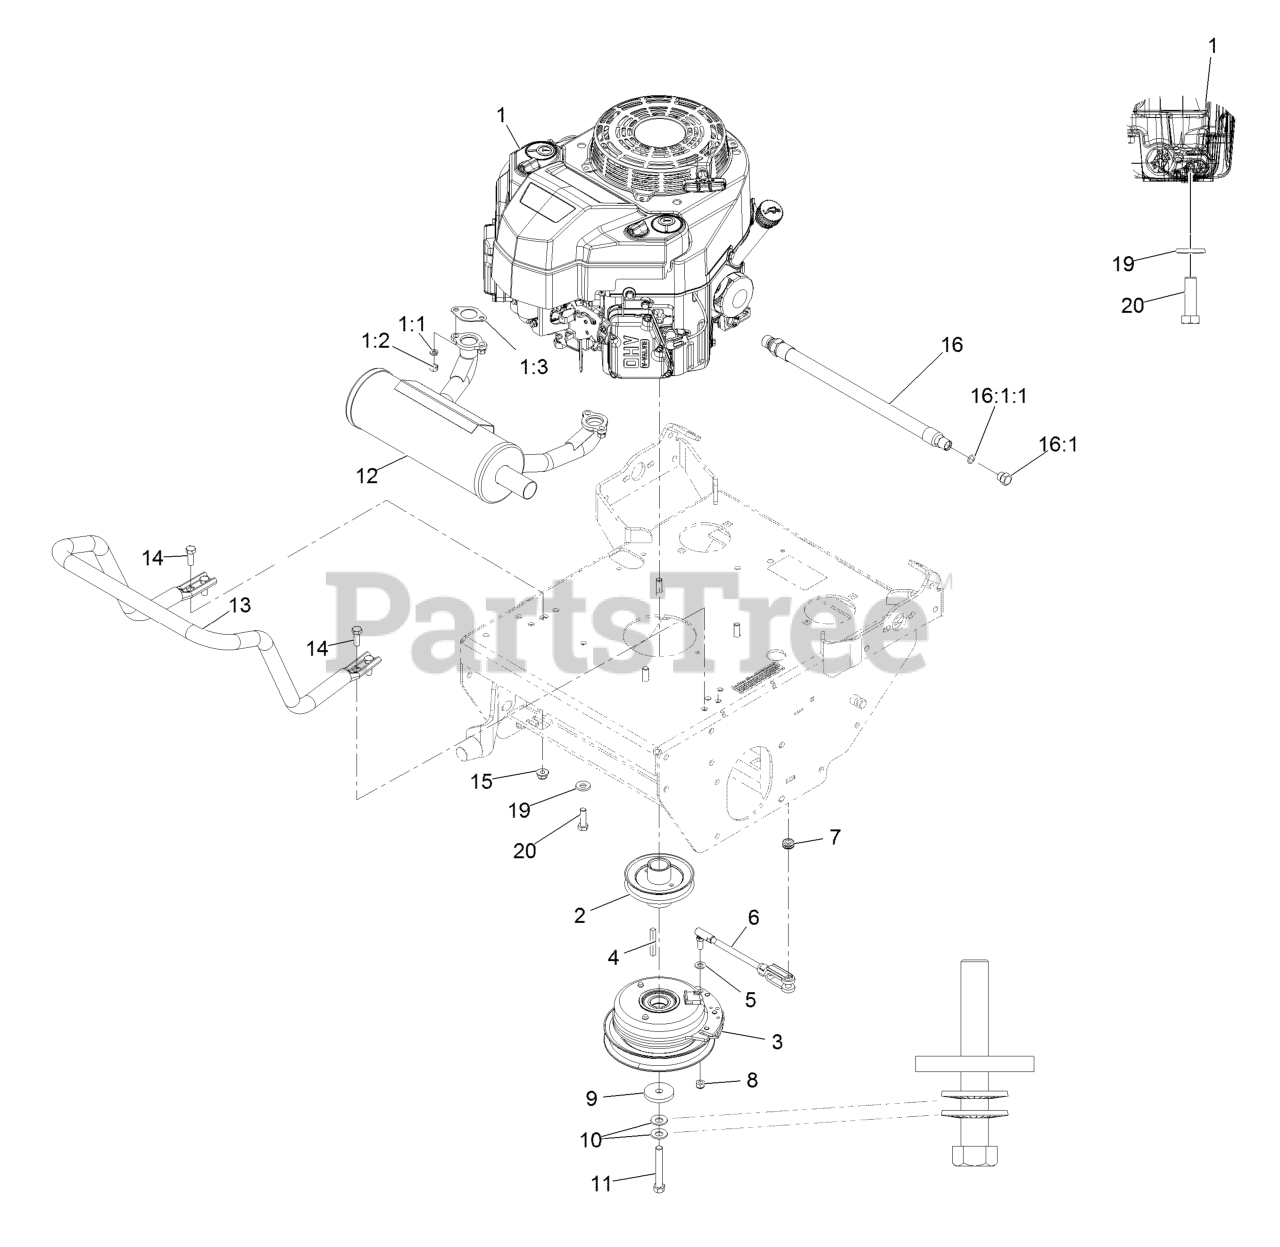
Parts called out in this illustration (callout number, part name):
1:1	Washer-Spring Lock M8
1:3	Gasket-Exhaust
2	Sheave, W/ Hub
3	Clutch, 105 Ft/Lbs, 1.13
4	Key-Machine 1/4 X 1/4 X 2
5	Washer-5/16 SAE
6	ASM, Clutch Anchor
7	Grommet
8	Nut-Lock 5/16-24
9	Washer-Clutch
10	Washer-Spring Disc 7/16
11	Screw-HH 7/16-20 X 3
12	Muffler-Horizontal
13	Guard-Muffler
14	Screw-HH 3/8-16 X 1
15	Nut-Nyloc 3/8-16 Flg
16	Asm-Oil Drain Hose W/Plug
16:1	Plug-W/O-Ring
16:1:1	O-Ring
19	Washer-Spring Disc 3/8
20	Screw-HH 3/8-16 X 1 1/4
